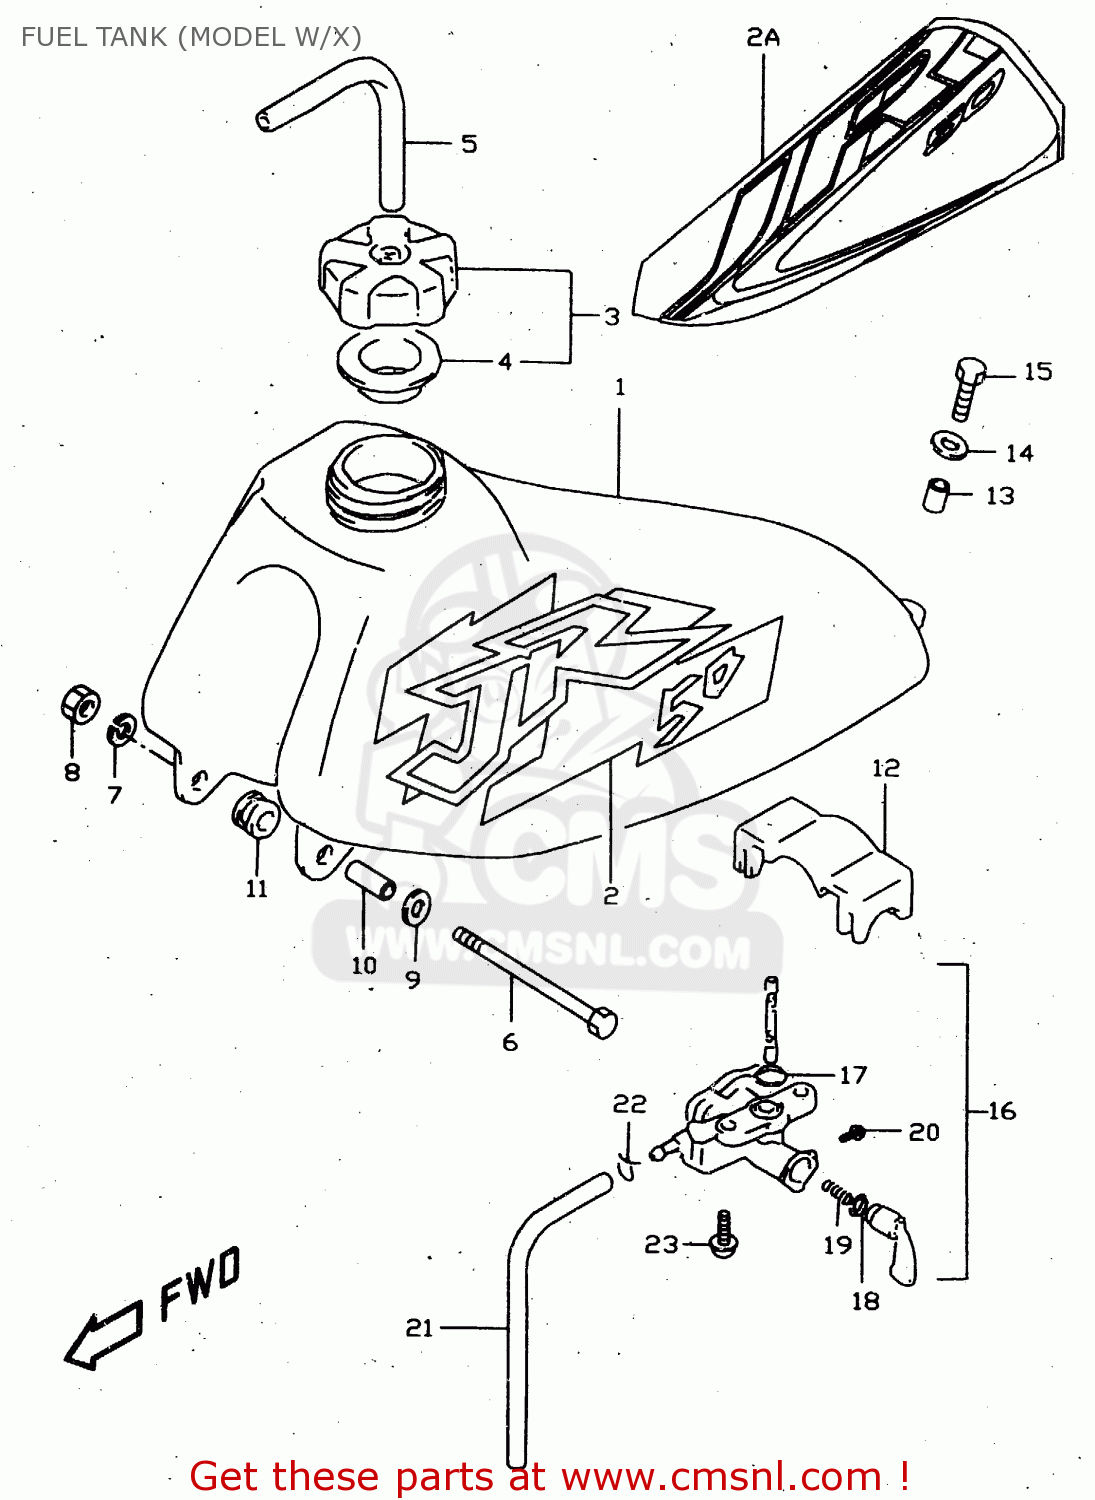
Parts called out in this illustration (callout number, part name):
1	TANK,FUEL
2	EMBLEM SET,FUEL TANK
2A	EMBLEM SET,FUEL TANK
3	CAP,FUEL TANK FILLER
4	GASKET (NAS)
5	HOSE(5X8.2X600)
6	BOLT, FRONT
7	LOCK WASHER
8	NUT 6MM
9	WASHER(6.5X18X1)
10	SPACER(6.5X10X11.5)
11	CUSHION
12	CUSHION,FUEL TANK UPR
13	SPACER(6.5X9X7.2)
14	WASHER(6.5X18X1)
15	BOLT
16	COCK ASSY,FUEL
17	O RING
18	O RING,LEVER
19	SPRING
20	SCREW
21	HOSE(5X8.2X600)
22	CLIP
23	SCREW
